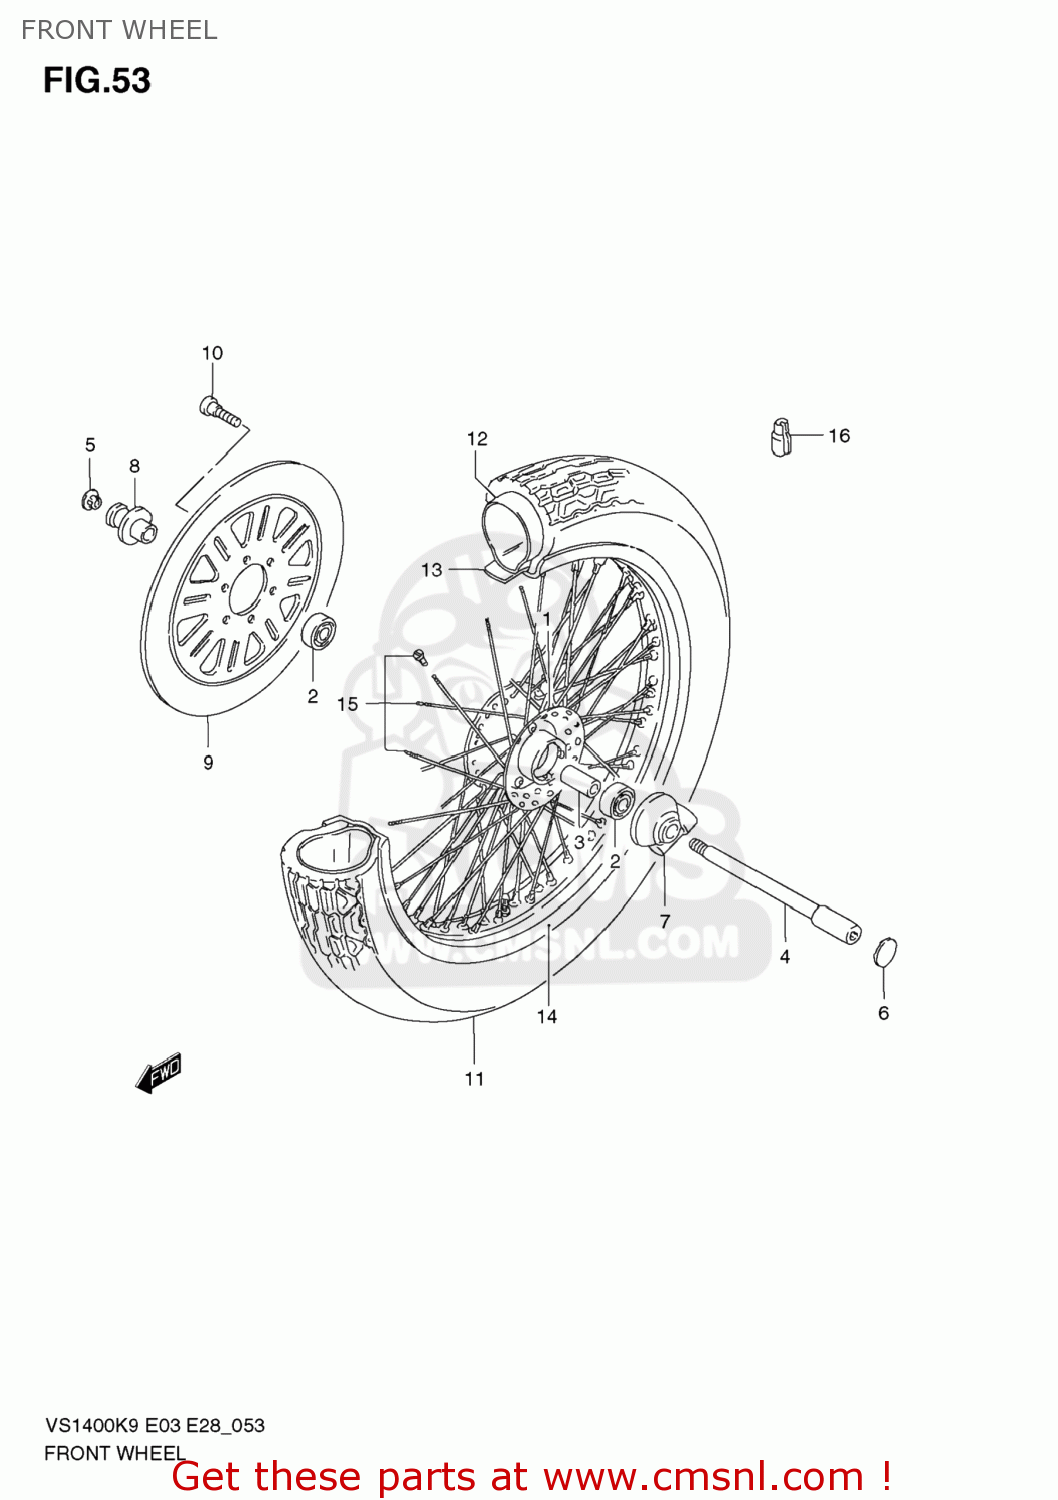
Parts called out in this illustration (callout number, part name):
1	HUB ASSY,FR
2	BEARING
3	SPACER(15.3X21.7X65)
4	AXLE,FR
5	CAP,FR AXLE
6	CAP,FR AXLE
7	BOX ASSY,SPEEDOMETER
8	SPACER,FR AXLE
9	DISC,FR BRAKE
10	BOLT(8X33)
11	TIRE,FR(110/90-19 62H)
12	TUBE ASSY,WHEEL INNER
13	PROTECTOR, INNER TUBE
14	RIM,FR WHEEL(19X2.15 AL)
15	SPOKE SET,FR WHEEL
16	BALANCER,WHEEL(30G)
